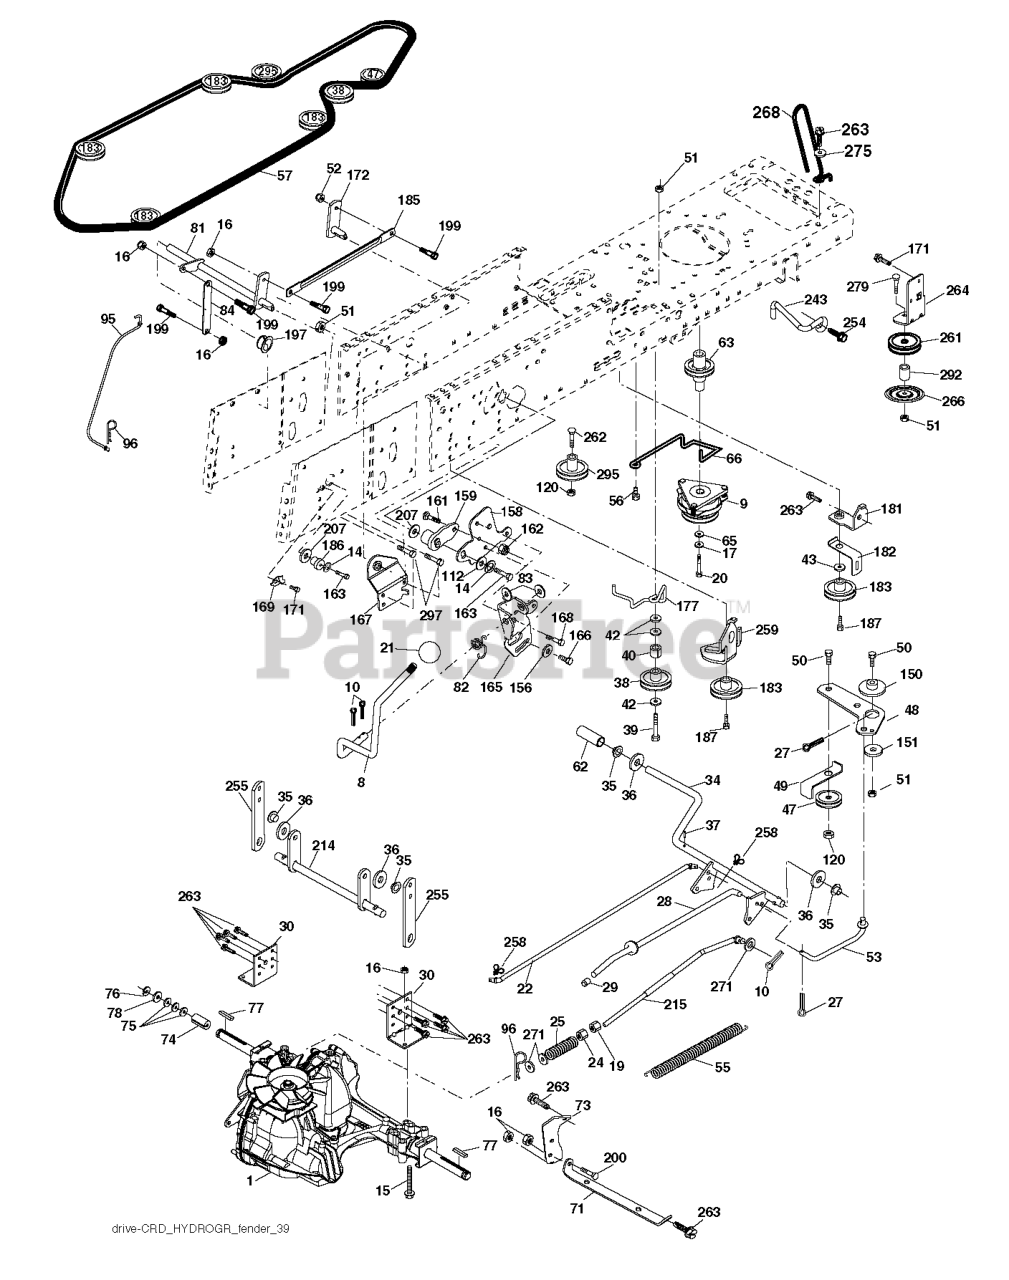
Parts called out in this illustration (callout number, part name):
8	ROD SHIFT FENDER ADJUST LT
9	CLUTCH.ELECTRIC.OGURA.EURO.
10	PIN COTTER
14	LOCKWASHER
15	BOLT HEX 5/16-18 GR 5
16	NUT.71038.31-18.HEX.NYLOCK
19	NUT
20	BOLT HEX 7/16-20X4-1/4"
21	KNOB.DUCKHEAD.1/2
22	ROD
24	NUT
25	SPRING BRAKE ROD
27	COTTER PIN
28	ROD, PARKING BRAKE
29	CAP.BRAKE.PARKING.RED (2 2)
30	BRKT, TRNSXLE MNT 20"
34	SHAFT, FOOT PEDAL
35	BEARING.NYLON
37	DRIVE PIN
38	PULLEY.FLAT
42	WASHER
47	IDLER PULLEY
48	BELLCRANK, CLUTCH
49	RETAIN BELT
50	BOLT.3/8-16X1.50
52	LOCKNUT
53	LINK.CLUTCH.7.66.2005
55	SPRING, RETURN LT
56	SCREW.3/8-16
57	V-BELT 113"
62	PEDAL COVER T
63	PULLEY.ENGINE.CVX.LT
65	LOCKWASHER
66	KEEPER BELT ENGINE
71	STRAP TORQUE LH HYDRO
73	STRAP TORQUE RH HYDRO
74	SPACER AXLE
77	SQUARE KEY
81	ASM.CROSS.SHAFT.REAR.CRD.0510
82	SHIFT SPRING
83	WASHER
84	LINK.PNT.TRANSAXLE.0510.CRD
95	LINK
96	RETAINER M
120	NUT LOCK FLG 3/8-16 UNC
150	BUSHING.BELLCRANK.GRD.DR
151	WASHER 12/32X2X10GA
156	WASHER.SRRTD.5/16
158	BRACKET.SHIFT.MOUNT
159	RB HUB.SHIFT
161	BOLT
162	NUT.CROWNLOCK.1/4
165	BRACKET.PIVOT.LEVER
166	CAPSCREW.HXHD.FLG.5/16-18X.625
167	BRACKET.SUPT.SHIFT.CRD
168	BOLT.SHOULDER.5/16-18X
169	PLATE.FASTENING.CROSS.SHAFT
172	LINK
181	BRACKET
182	BELT GUIDE
183	PULLEY.V-IDLER.
185	LINK
186	HUB.TAPERED.ROUND.CRD
187	BOLT.5/16-18X1.25
197	NYLINER SNAP 5/8" ID
199	BOLT SHOULDER 5/16-18 UNC
207	WASHER NYL
214	LEVER
215	ROD
243	BRACKET, ANTI-ROTATION
254	SCREW 3/8-16X1
255	SHAFT
258	CLIP RETAINER
259	BRACKET
261	FLAT IDLER PULLEY
263	SCREW, 3/8-16X3/4
264	BRACKET.IDLER
266	PROTECTOR
268	GUARD MUFFLER
271	WASHER
275	WASHER
292	SPACER
295	PULLEY IDLER COMPOSITE
297	SCREW LT.3/8-46X5/8
